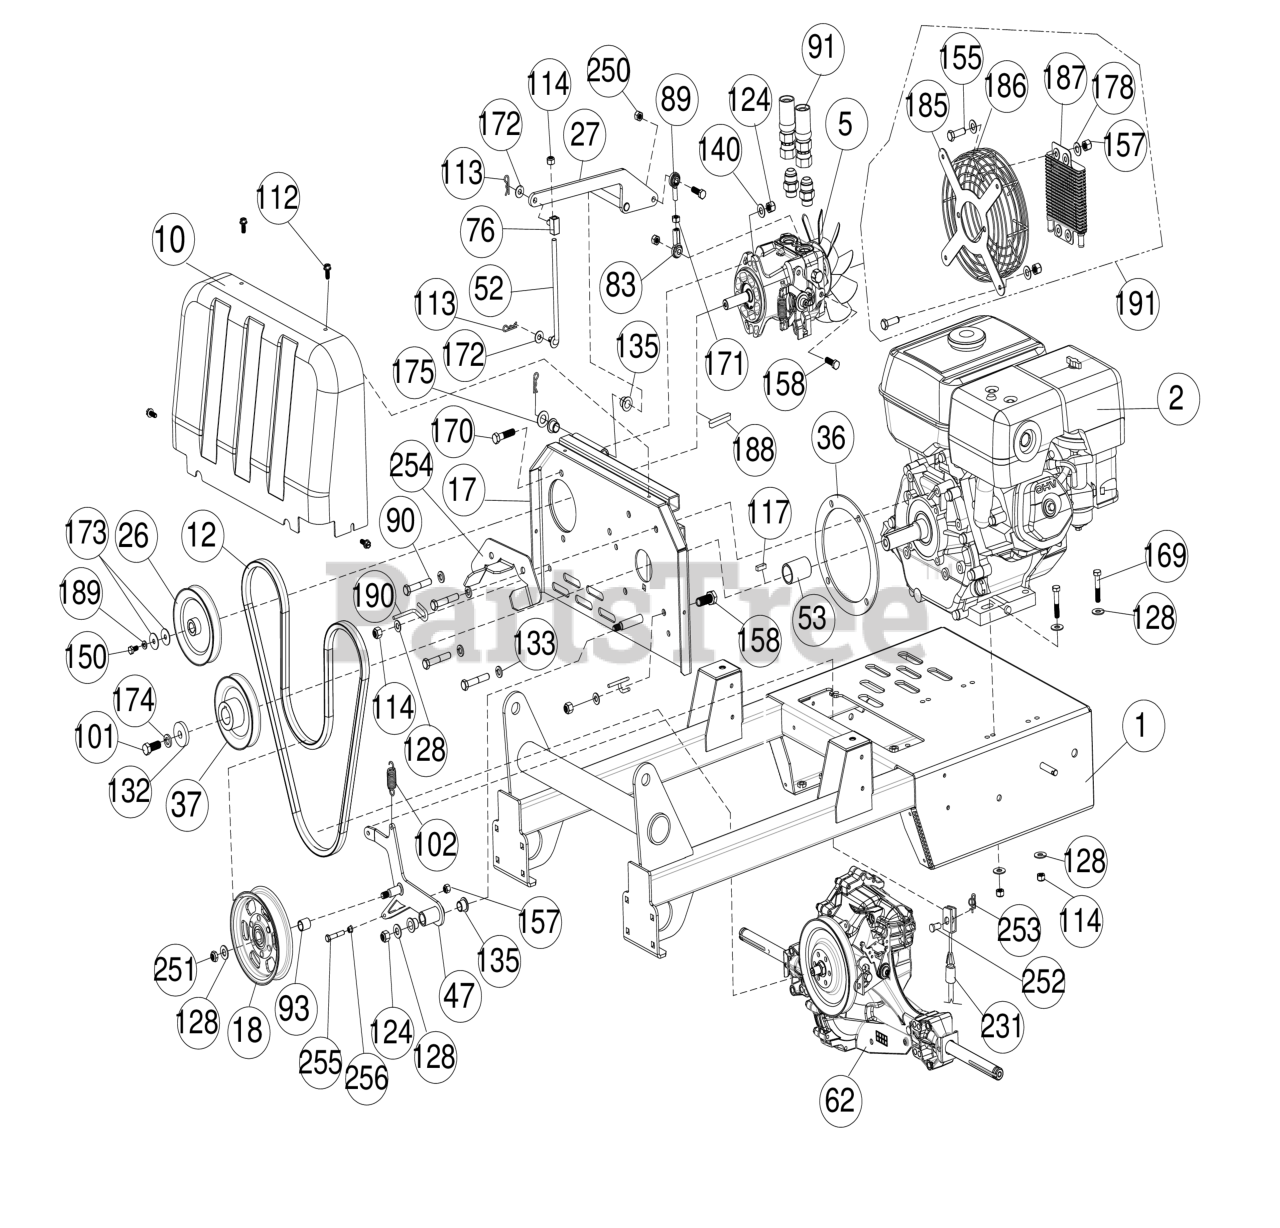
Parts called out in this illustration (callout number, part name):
1	ENGINE BASE WA W/LABELS AE1300H
2	ENGINE HONDA GX390 13 HP
5	PUMP PK 12CC VARIABLE DISPLACEMENT
10	GUARD BELT AE900
12	BELT HP GP AMD EFF. LENGTH 64.04"
17	PLATE PUMP MOUNT
18	PULLEY 5.00" OD FLAT IDLER
26	PULLEY 4.75 OD X .591 ID 5L
27	ARM ENGAGE PUMP WA
36	SPACER ENGINE WA DL18
37	PULLEY 4.50 O.D. X 1.00" I.D. - 5L
47	IDLER ARM WA AE900
52	ROD PUMP ENGAGE
53	SPACER ENGINE CRANKSHAFT
62	TRANSAXLE AE900
76	END ROD SLIDING
83	SPHERICAL ROD END MSF-5
89	SPHERICAL ROD END MSM-5
90	SCREWCAP 3/8"-16X2" HCS ZP
91	HOSE HYDRAULIC W#10 JIC
93	SPACER .75 OD X 11 GA
101	SCREWCAP 7/16-20 X 1" HCS GR. 8 W/PATCH
102	SPRING EXTENSION
112	SCREW SELF TAP 1/4"-20 X 5/8" HWH TYPE F
113	PIN HAIR 1/4" Z/P
114	NUT LOCK 5/16"-18 HEX Z/P
117	KEY SQUARE 1/4" X 1"
124	NUT LOCK 3/8"-16 HEX
128	WASHER 5/16" FLATWASHER Z/P
132	WASHER 1.5 OD X .453 ID X .25 THK
133	WASHER LOCK 3/8" S/T MED
135	BUSHING .500" ID
140	WASHER 3/8"SAE 13/32"X13/16"X1/16"
150	SCREWCAP M6 X 14
155	SCREWCAP 1/4"-20X3/4" HCS ZP
157	NUT LOCK 1/4"-20 HEX Z/P
158	SCREWCAP 5/16"-18 X 1" HCS ZP
169	SCREWCAP 5/16"-18X1 3/4" HCS ZP
170	SCREWCAP 3/8" - 16 X 1/2" HCS ZP
171	NUT 5/16"-18 FIN HEX Z/P
172	WASHER 1/4" FLAT Z/P
173	WASHER FLAT FENDER 1/4"
174	WASHER LOCK 7/16" S/T MED
175	WASHER 1/2" FLAT KD WHEEL MTG
178	WASHER 1/4"SAE9/32"X5/8"X1/16"
185	BRACKET GUARD FAN
186	GUARD WIRE PUMP FAN
187	COOLER OIL
188	KEY FEATHER 5MM X 5MM X 30MM
189	SEE: 812240-7
190	SEE: 812240-7
191	KIT, FAN/HUB HYDRO GEAR 70811
231	SEE: 362276-S
250	NUT LOCK 5/16"-18 LT WT TH ZP
251	NUT LOCK 3/8-16 LT WT THIN ZP
252	PIN CLEVIS 1/4" X .75"
253	1/4" RUE RING
254	BRACKET BELT GUILD UPPER
255	SCREWCAP 1/4"-20X2" HCS ZP
256	NUT WHIZ 1/4"-20 WASH FACE
